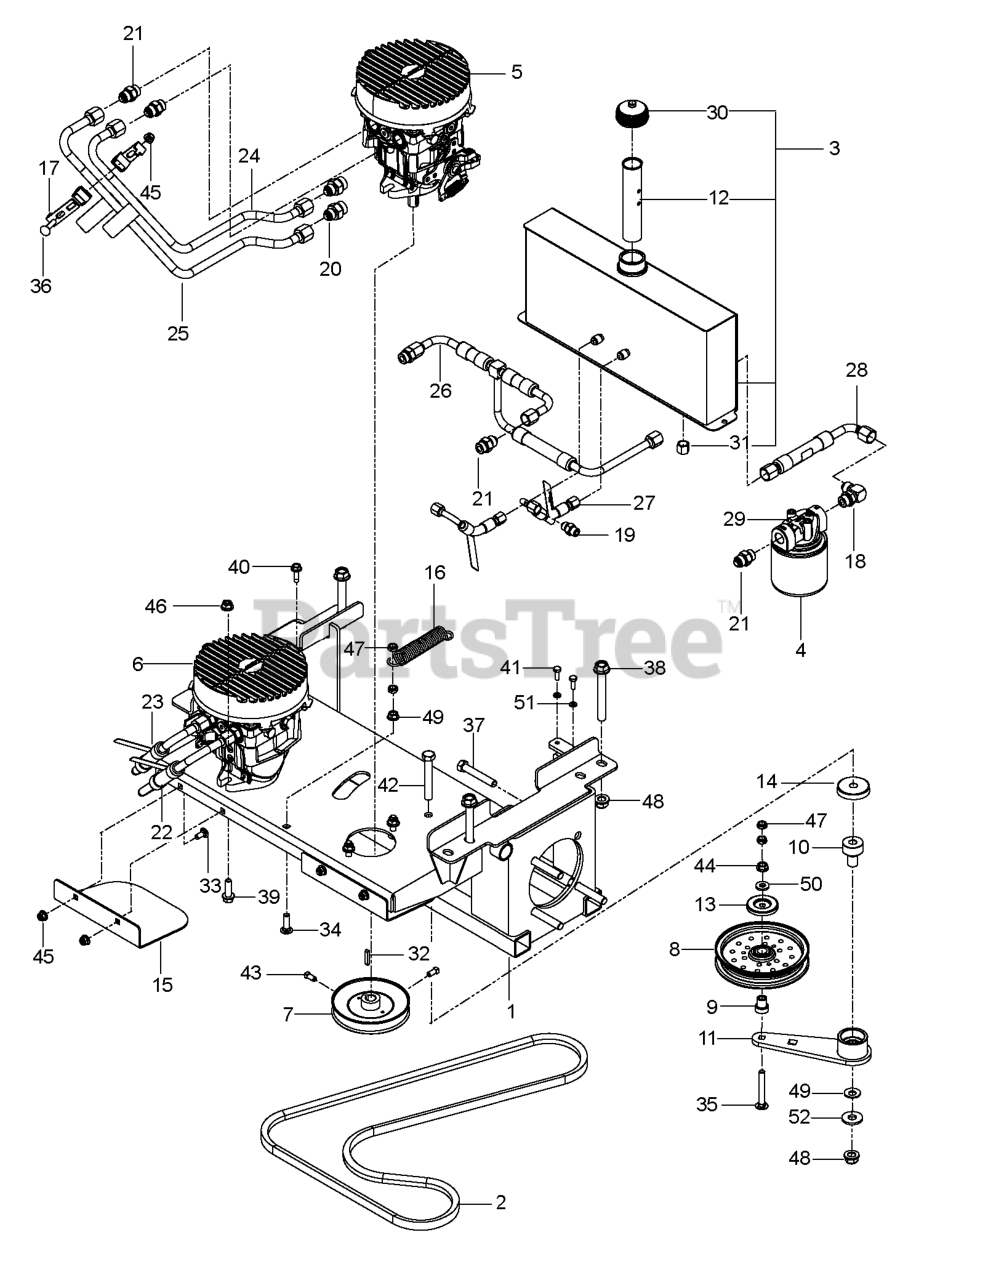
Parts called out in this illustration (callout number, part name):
1	FRAME, NYDR SUB, BLK
2	BELT, "B", 75.5"
3	ASSEMBLY, RESERVOIR, OIL
4	FILTER 25 MICRON
5	HG_PUMP, 16CC
6	HG_PUMP, 16CC
7	PULLEY, PUMP 17MM
8	IDLER, FLAT, 5.5"
9	PIVOT, IDLER
10	PIVOT, BEARING
11	ARM, IDLER, STEEL, W/BGS
12	TUBE, ANTI-SPLASH
13	DUST SHIELD
14	SHIELD, DUST
15	SHIELD, PULLEY, BLK
16	SPRING, PUMP
17	ASM, VIB, HYDRO HOSE
18	ELBOW, 90 DEGREE
19	STRAIGHT FITG
20	CONNECTOR, STRAIGHT
21	FITTING, STRAIGHT F6400-8-8-0
22	LINE, RT A
23	LINE, RT B
24	LINE, LT A
25	LINE, LT B
26	LINE, CHARGE
27	LINE, CASE
28	LINE, SUCTION
29	FILTER HEAD
30	CAP, HYDRAULIC
31	NUT 9/16-18 JIC CAP
32	KEY 5 MM SQ X 25 MM
33	RP BOLT 5/16-18 X3/4 ZN/YEL GR
34	BOLT.3/8-14X1.25
35	BOLT
36	BOLT
37	HCS 1/2-13 X 2-3/4 GD 5 ZD
38	HHFS 1/2-13 X 4.0 GD8 ZD
39	HHFS 3/8-16 X 1.25 GD 5
40	SCREW
41	HCS 1/4C X 5/8
42	HCS 1/2C X 3 1/4
43	SCREW 5/16C X 5/8 SQ HEAD
44	NUT 3/8C WHIZ
45	5/16-18 NYLOC FLANGE NUT
46	NUT 3/8-16 HEX FLG NYLOC ZD
47	NUT HEX 3/8-16 NYLON, THIN
48	NUT, 1/2-13 HEX FLG NYLOC ZD
49	CONTACT BELLSPR 1/2
50	WASHER, 3/8 THICK
51	LOCKWASHER 1/4"
52	WASHER.9/16 X 1 3/8 X 12 GA.
